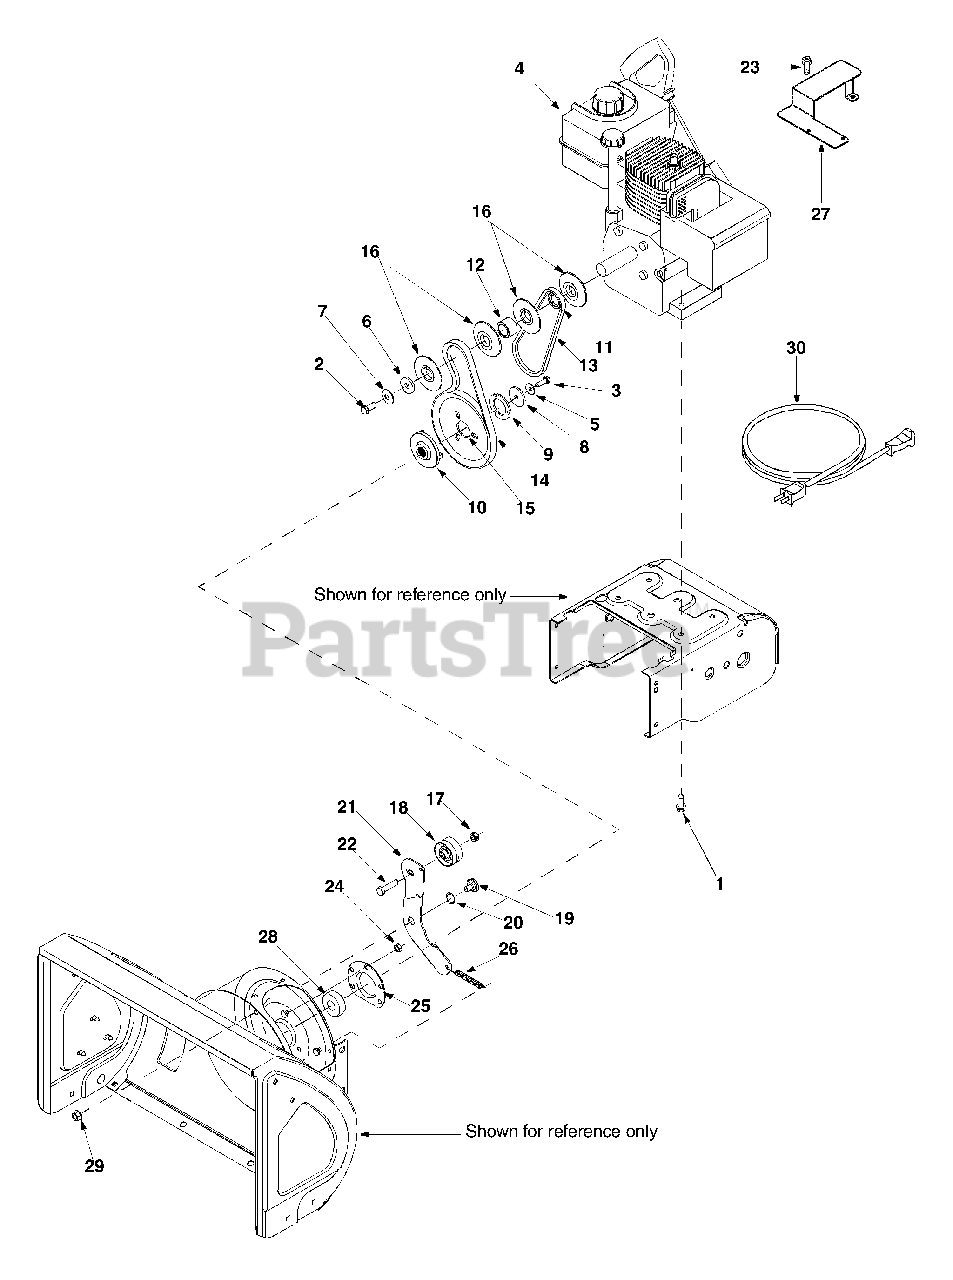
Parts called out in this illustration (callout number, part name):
1	TT Sems Screw 3/8-16 x 1.0"
2	Hex Bolt 3/8-24 x 0.875"
3	Lock Bolt 5/16-24 x 0.875"
4	Engine
5	Bell Washer,.340 x.872 x.060
6	Flat Washer,.406ID x 1.25OD
7	Bell Washer,.390 x 1.13 x.062
8	Flat Washer,.34ID x 1.50OD
9	Special Washer, 1.285 x 2.0 x.119
10	Pulley: Adapter,.75 Dia.
11	Spacer,.8760ID x 1.25OD x.1900
12	Spacer,.8760ID x 1.25OD x.86
13	V-Belt, 3/8 x 21.108 Lg.
14	V-Belt, 3/8 x 26.680 Lg.
15	Auger Pulley
16	Pulley Half
17	Hex Lock Nut 3/8-16
18	Flat Idler
19	Shoulder Screw 3/8-16
20	Wave Washer
21	Auger Idler Bracket
22	Hex Bolt 3/8-16 x 1.50"
23	Screw, #10-16 x.500
24	Flange Lock Nut, 5/16-18
25	Bearing Housing
26	Extension Spring
27	Heat Shield
28	Ball Bearing
29	Flange Lock Nut, 3/8-16
30	Extension Cord: 110V, 3-prong
